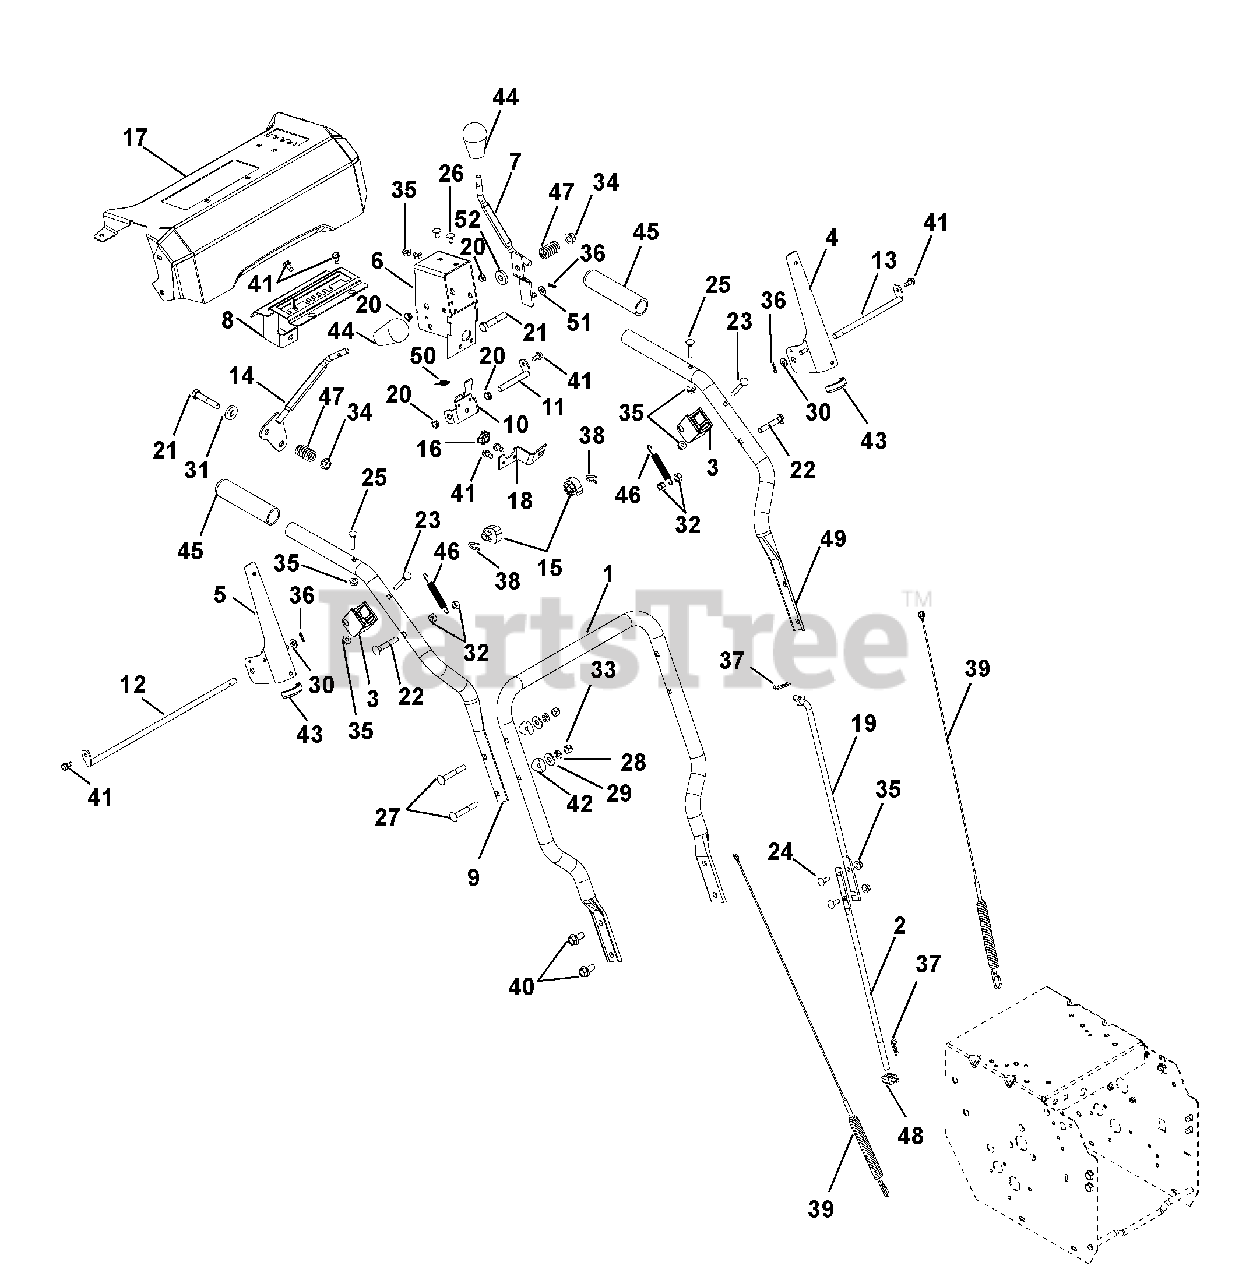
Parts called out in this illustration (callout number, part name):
1	HANDLEBAR, LOWER (COMPACT)
2	ROD, SHIFT - LOWER
3	BLOCK, CLUTCH PADDLE
4	LEVER, CLUTCH-LH
5	LEVER, CLUTCH-RH
6	WELDMENT, BRACKET INTERLOCK
7	WELDMENT, CONTROL LEVER (DEFL)
8	WELDMENT, DETENT PLATE-COMPACT
9	HANDLEBAR, UPPER - RH
10	BRACKET, INTERLOCK ARM
11	ROD, PIVOT - INTERLOCK
12	ROD, PADDLE MOUNT - LONG
13	ROD, PADDLE MOUNT - SHORT
14	LEVER, CONTROL-SHIFT(WELDMENT)
15	CAM, INTERLOCK
16	CRANK BUSHING, NYLON CHUTE BK
17	CTRL PANEL W/DECAL SNO-TEK MAN
17	CTRL PANEL W/DECAL,SNO-TEK,REM
18	ANCHOR, DEFLECTOR CABLE
19	ROD, SHIFT - UPPER
20	BUSHING, POLYLINER-.38 SNAPIN
21	@BLT-HEX .38-16X2.00 GR5 YWZC
22	BLT-RDHDXLSQNK .31-18X2.0 G5YZ
23	BLT-RDHDXLSQNK .25-20X2.0 G5YZ
24	@BLT-RDHDSQNK .25-20X.75 G5YZ
25	BLT-RDHDXLSQNK.25-20X1.25 G5ZC
26	@BLT-RDHDSQNK .25-20X.50 G5YZ
27	@BLT-RDHDSQNK .31-18X2.25 G5YZ
28	WSHR-LK .312X.097 HVY YWZC
29	@WSHR-FL-STL.38X.875X.083 YWZC
30	@WSHR-FL-STL.281X.62X.065 YWZC
31	WSHR-FL-STL .406X1.00X.188 YWZ
32	@NUT-LK-CTR .31-18 YWZC
33	@NUT-LK-NYL .312-18 YWZC
34	@NUT-LK-TOP-FLG .38-16 YWZC
35	@NUT-LK-CTR-FLG .25-20 YWZC
36	PIN-HAIR INT .06X.18X.77
37	PIN-HAIR INT .08X.18X1.18 YWZC
38	PIN, SPRING CLIP
39	CABLE, AUGER & UPPER TRACTION
40	BLT-SERHFWH .38-16X.75 YWZC
41	SCR-TAP .25-20X.50 HWH TR YWZ
42	SPACER, HANDLEBAR
43	EDGING, CLUTCH PADDLE - 2.00"
44	KNOB,SOFT TEARDROP,PUSH-ON BLK
45	HANDLE GRIP
46	SPRING, EXTENSION
47	SG-COMP .125X.781X1.250
48	PIVOT,SHIFT ROD .375-16(TRUNN)
49	HANDLEBAR, UPPER - LH
50	SPRING-EXT .047X.438X1.45
51	BSHG-SLV .265X.500X.219
52	WSHR-FL-STL .380X1.50X.062 YWZ
